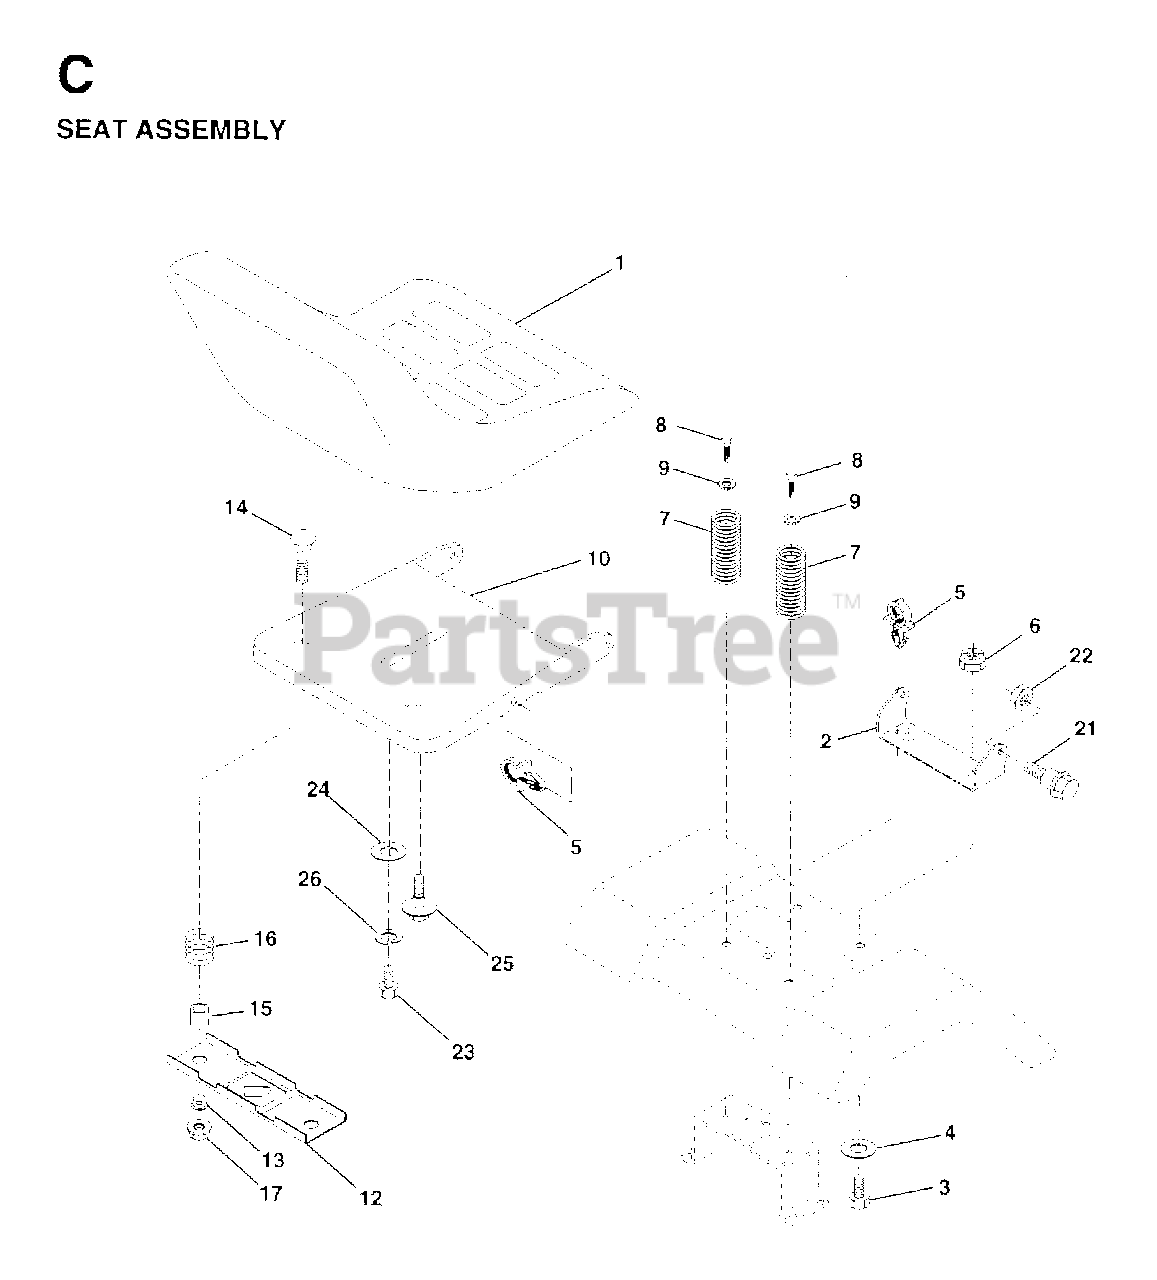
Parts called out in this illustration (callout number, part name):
1	SEAT
2	SEAT PIVOT BRKT
3	BOLT
4	WASHER PM
5	PUSH CLIP
6	NUT
7	SPRING COMPRESSION
8	SCREW GTV
9	WASHER
10	PAN, SEAT
12	BRKT SWITCH
14	BOLT CARRIAGE 1/4-20X1 3/8
15	SPACER SPLIT
16	SPRING COMPRESSED
17	NUT T
21	BOLT SHOULDER 5/16-18
22	NUT.71038.31-18.HEX.NYLOCK
23	BOLT
25	BOLT,SHOULD
26	LOCKWASHER
